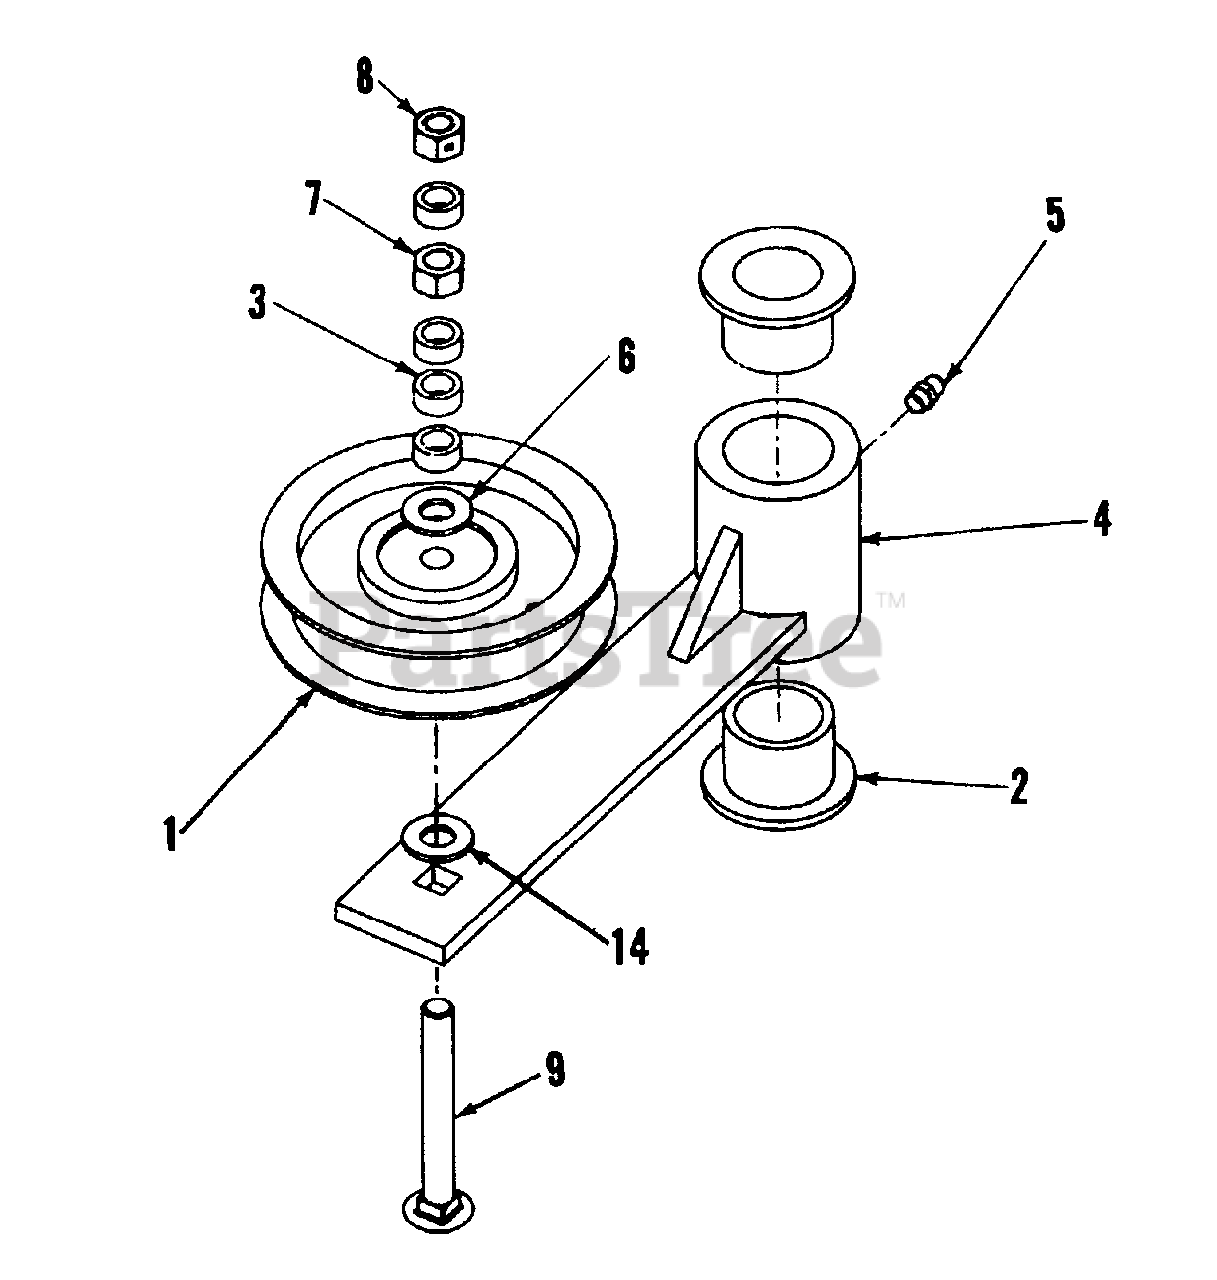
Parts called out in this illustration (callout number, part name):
1	FLAT IDLER, 4-1/8"
2	BUSHING, Caster
3	SPACER, Tie Rod
4	WELDMENT, Idler Arm
5	FITTING, Lube 1/4-28 Straight
6	WASHER, 3/8" Flat
7	NUT, 3/8-16 Hex, Grade 5 or B
8	NUT, 3/8-16 Hex Center Lock, Grade 5 or B
9	BOLT, 3/8-16 x 3", Round Head Square Neck Grade 5
14	WASHER, 3/8" Flat
